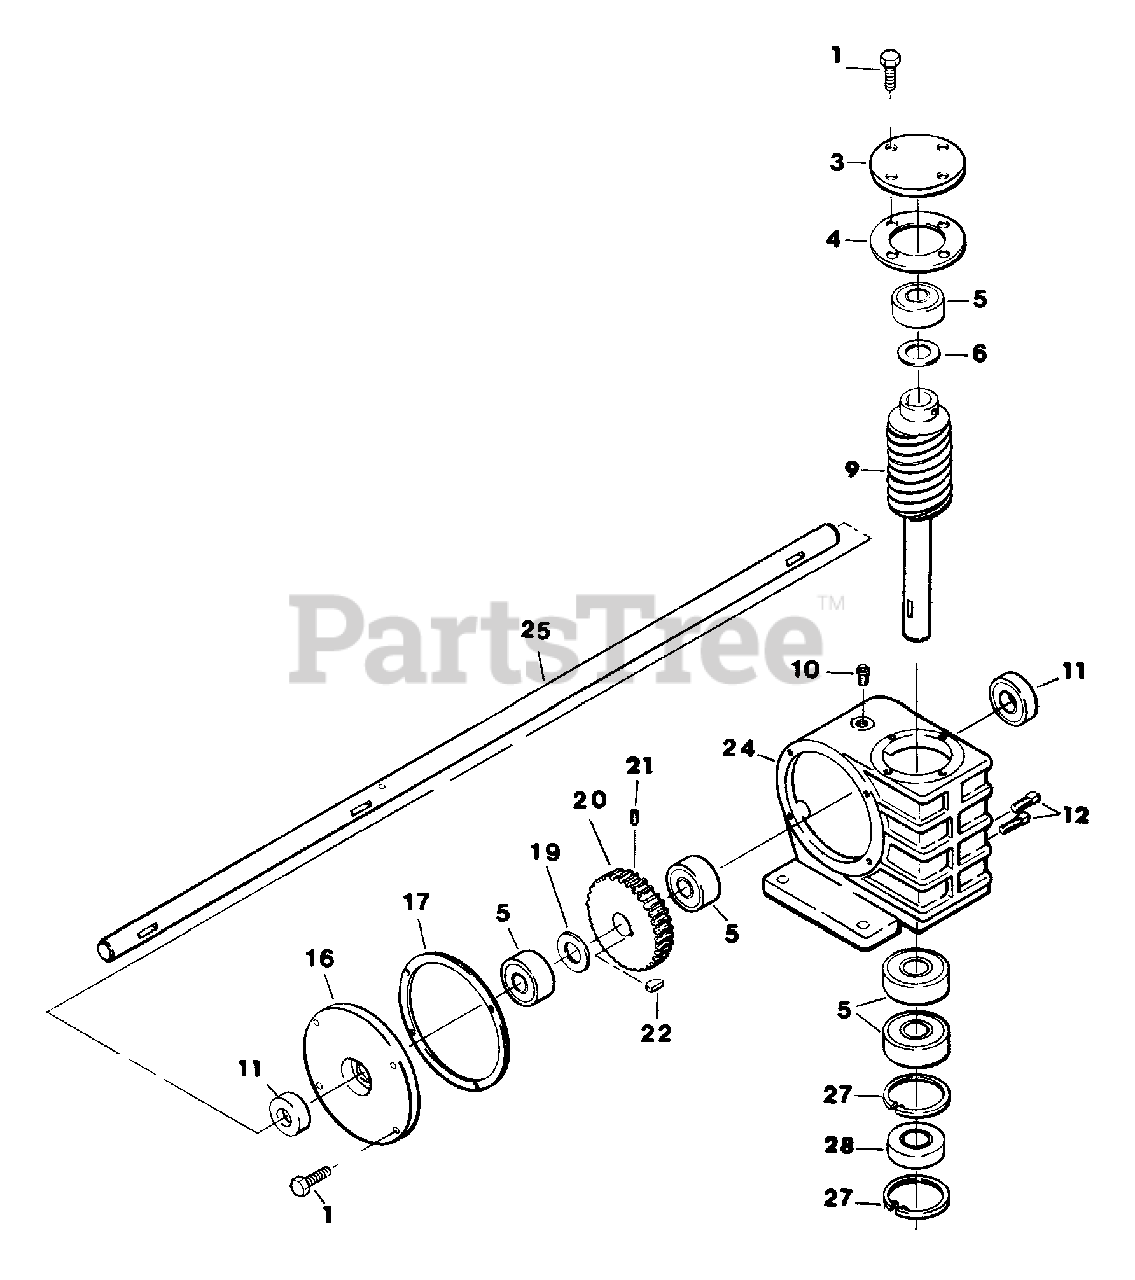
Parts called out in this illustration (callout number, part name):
1	1/4"-20X5/8" Hex Hd. Cap Screw
3	Input Cover w/Brg (P/N 77324)
4	Input Gasket
5	Bearing
6	Shims 5/8"x7/8"x.010
9	Worm Gear Assy
10	Vent Plug
11	Seal, Output
12	Pipe Plug 1/8"-27
16	Output Cover w/Brg (P/N 77324)
17	Output Gasket
19	Shims 5/8"x7/8"x.005
21	1/4"-20x3/8" Set Screw
22	#5/405 Woodruff Key
24	Gear Case
25	Output Shaft
27	Snap Ring
28	Seal, Input
